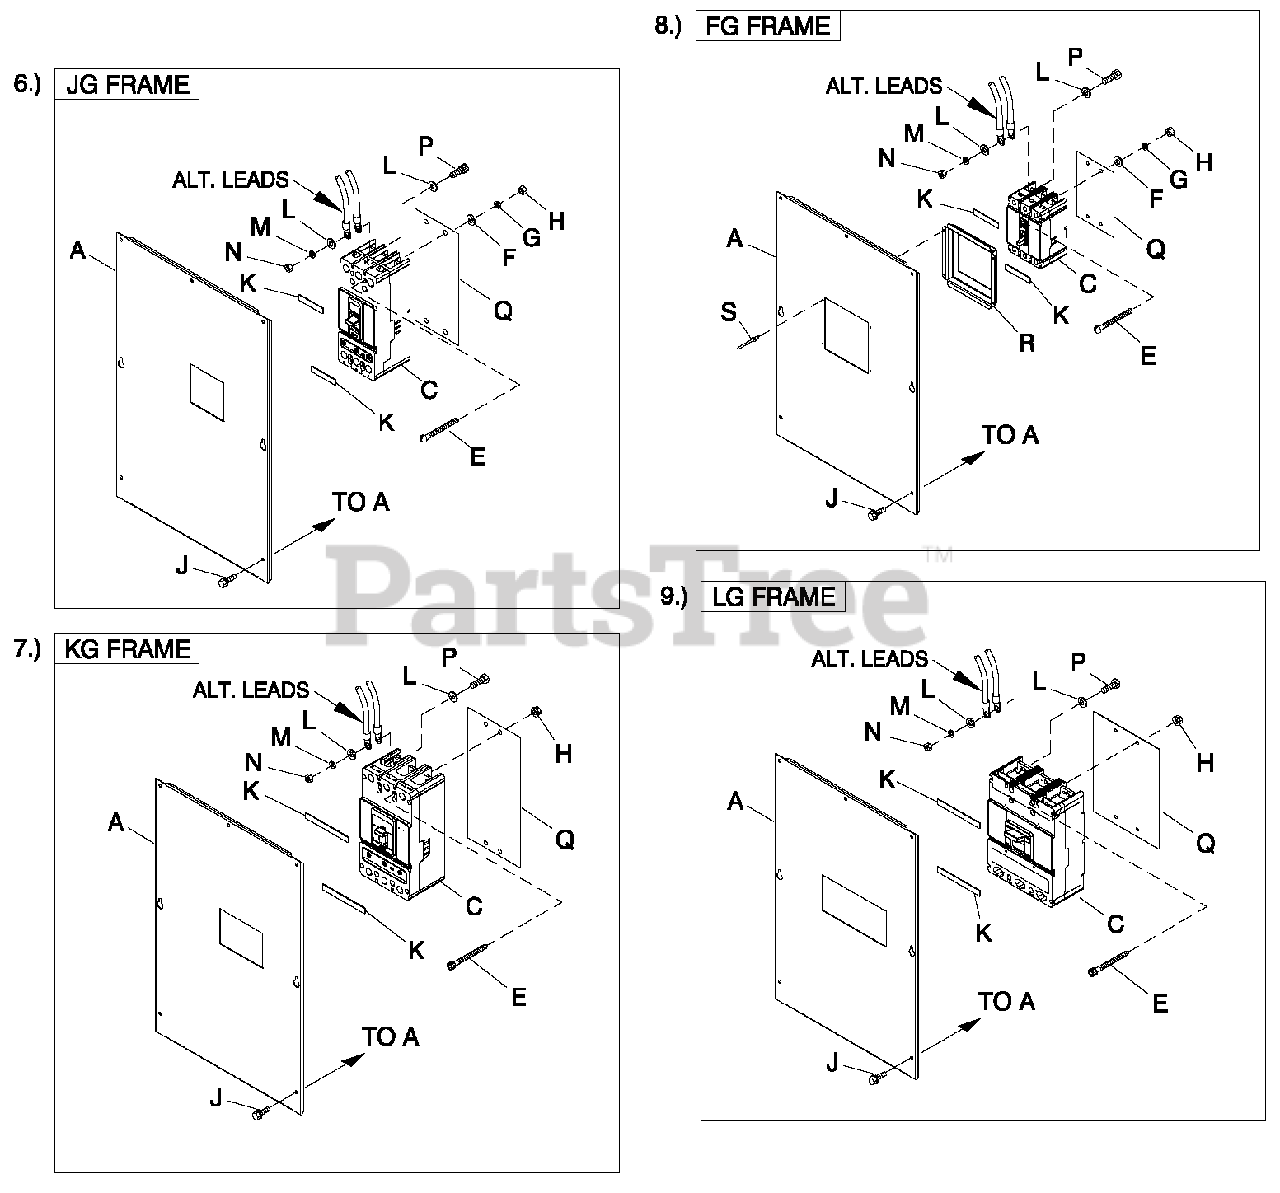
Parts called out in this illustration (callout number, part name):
6	UL CIRCUIT BREAKER (JG)
7	UL CIRCUIT BREAKER (KG)
8	UL CIRCUIT BREAKER (3P FG)
9	UL CIRCUIT BREAKER (LG)
A	COVER CB E JG FRAME C5
C	CB 0250 3P 600V E JG LL
E	SCREW RHM 1/4-20 X 3
F	WASHER FLAT 1/4-M6 ZINC
G	WASHER LOCK M6-1/4
H	NUT HEX 1/4-20 STEEL
J	SCREW THF M6-1 X 16 N WA Z/JS
K	TAPE ELEC 1/2 FOAM
L	WASHER FLAT 5/16-M8 ZINC
M	WASHER LOCK M8-5/16
N	NUT HEX M8-1.25 G8 CLEAR ZINC
P	SCREW HHC M8-1.25 X 25 C8.8
Q	INSULATOR CB E 3P JG
A	COVER CB E KG FRAME C5
C	CB 0350 3P 600V E KG LL
E	SCREW SHC M6-1.0 X 50 C8.8
H	NUT FLANGE M6-1.0 NYLOK
Q	INSULATOR CB E 3P KG
A	COVER CB G 225AF C5
C	CB 0150 3P 480V E FG LL
E	SCREW PPHM #8-32 X 1-3/4 ZINC
F	WASHER FLAT #8 ZINC
G	WASHER LOCK #8-M4
H	NUT HEX #8-32 STEEL
L	WASHER FLAT #10 ZINC
M	WASHER LOCK M5
N	NUT HEX M5-0.8 G8 CLEAR ZINC
P	SCREW HHC M5-0.8 X 20 G8.8
Q	INSULATOR CB 3P E TYPE CC/FG
R	COVER CB DISH 3P E FD
S	RIVET POP .125 X .275 SS
A	COVER CB E LG FRAME C5
C	CB 0450A 3P 600V E LG LL
Q	INSULATOR CB E 3P LG
